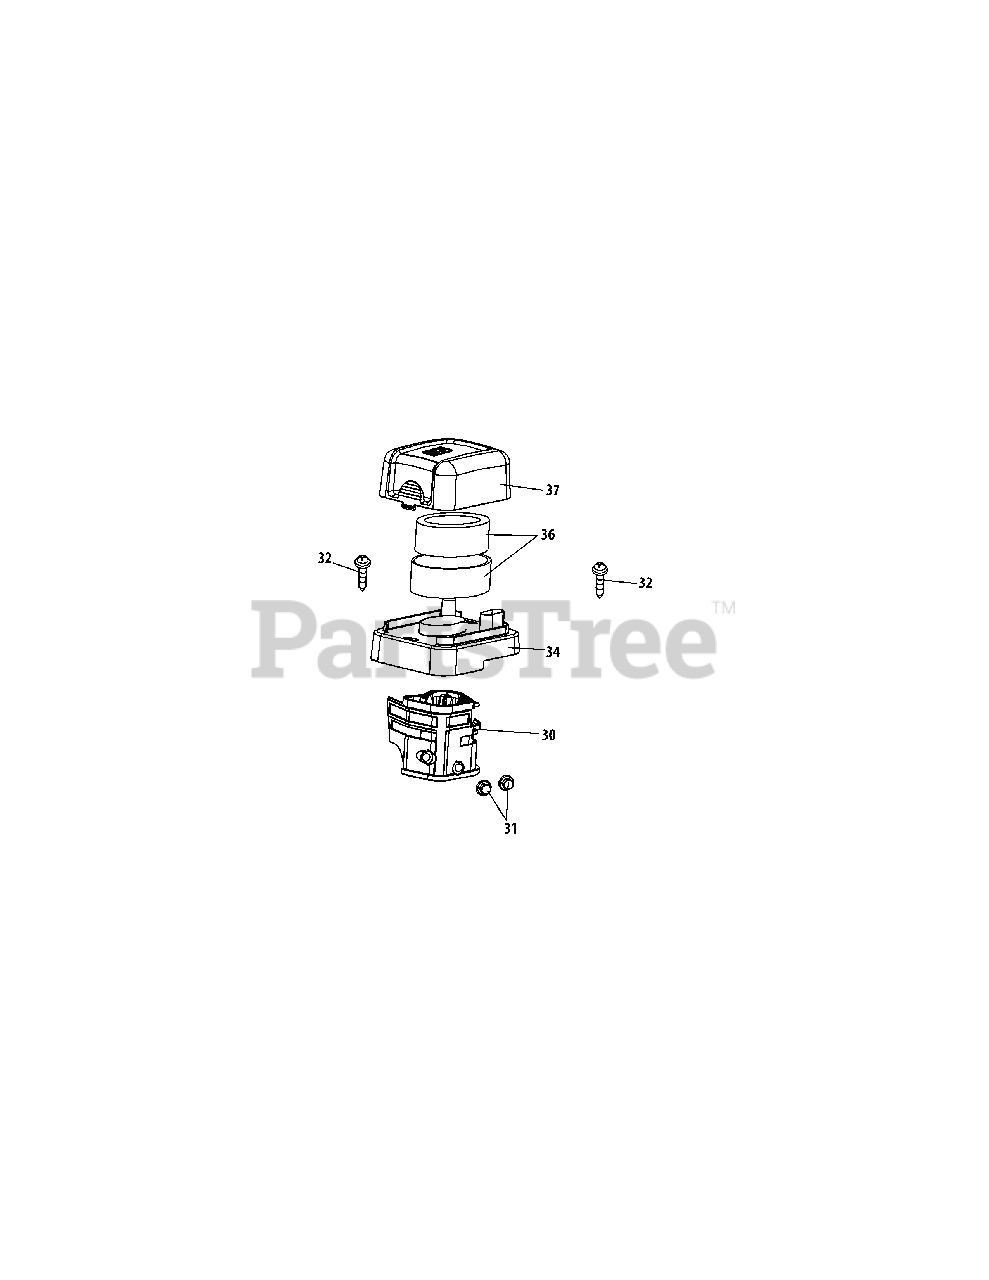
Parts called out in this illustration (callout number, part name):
30	Air Cleaner Housing
32	Self-Tapping Bolt M4.2×16
34	Silencer Plate
36	Air Cleaner Filter Assembly
37	Air Cleaner Cover
